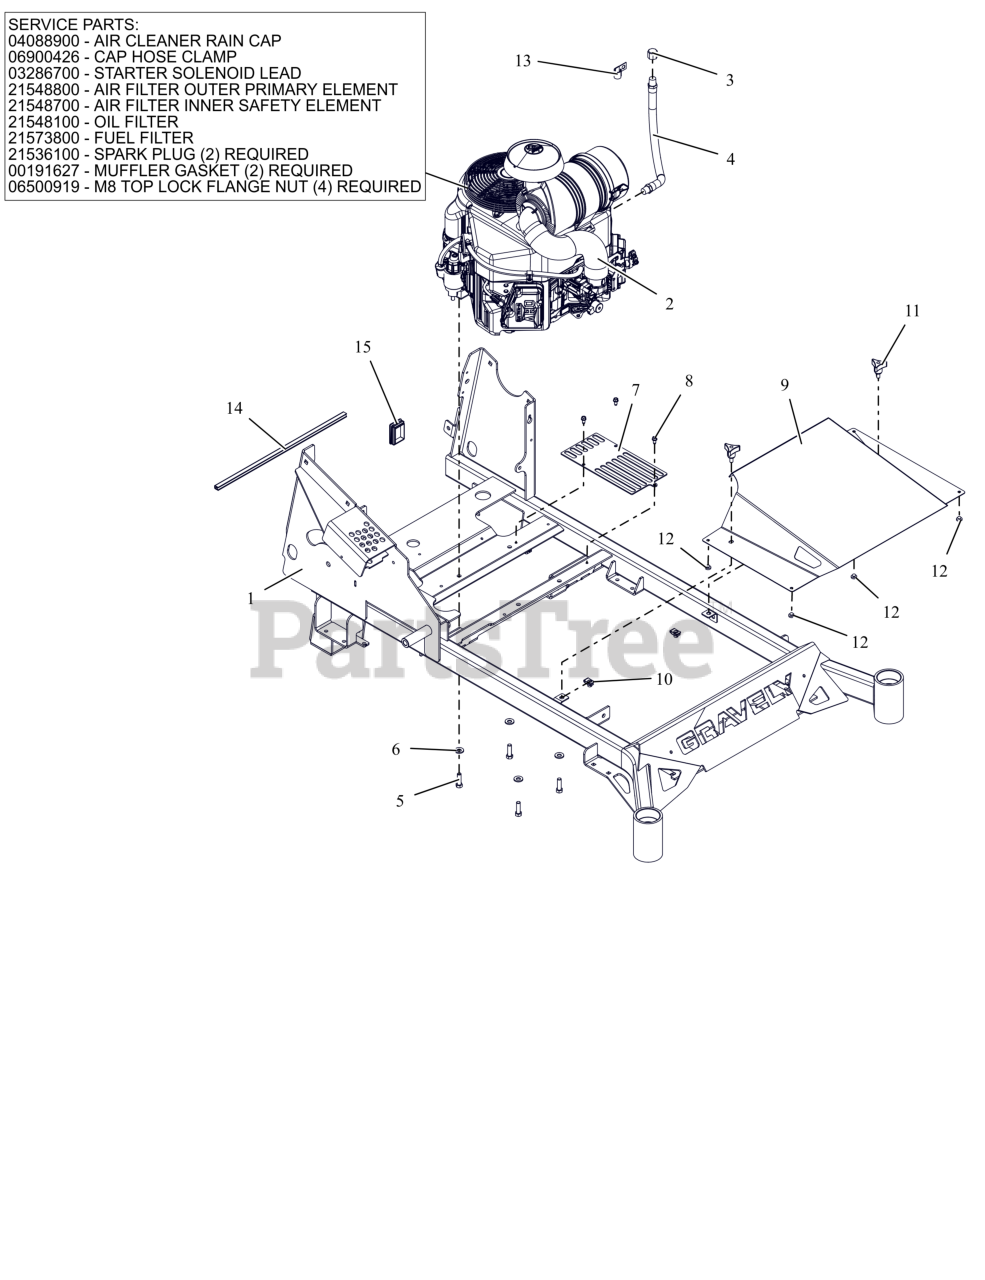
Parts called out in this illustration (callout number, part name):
1	WLDMT, PROSTANCE MAIN FRAME (RED)
2	ENGINE, KAWASAKI
2	CAP, KAW 11065-7025
2	CLAMP, HOSE #36 SS 1.813-2.75
2	LEAD - STARTER SOLENOID
2	FILTER, OUTER
2	FILTER, INNER - KAW
2	OIL FILTER, KAWASAKI FR
2	FUEL FILTER
2	PLUG, SPARK
2	GASKET, MUFFLER S/O
2	NUT-LK-TOP-FLG M8 ZCC
3	PIPE CAP 3/8 NPT FEMALE
4	DRAIN, M20 OIL
5	BLT, HEX .38-16X1.25 G5 ZCC NT
6	WASHER, 3/8" SPRING DISC
7	GUARD, TRANSAXLE FAN (RED)
8	SCR-TAP .25-20X.50 HWH ZCC
9	COVER, BELT
10	NUT-CLIP RETAINER 5/16-18X.56
11	KNOB,WING STUD 5/16-18 X .75
12	BUMPER GROMMET
14	STRIP, COWL
15	PLUG, RECT 1.575 x 2.362
